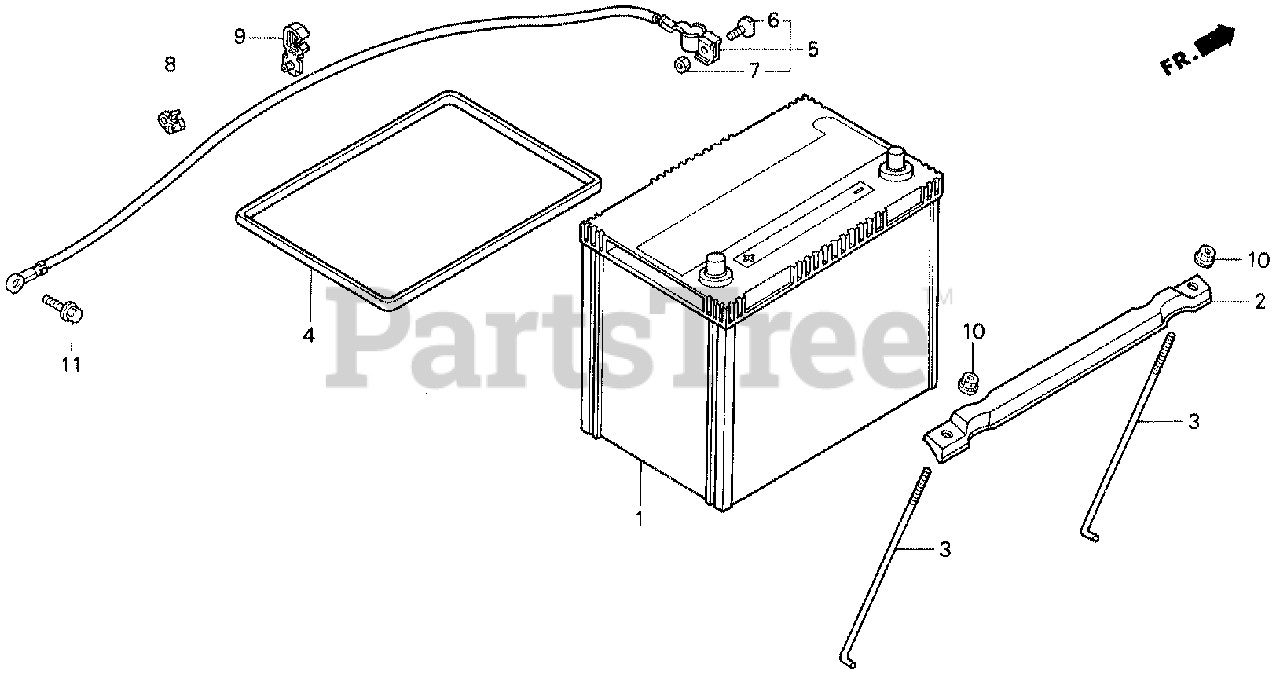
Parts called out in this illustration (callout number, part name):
1	BATTERY ASSY. (55B24R S-MF) (YUASA) (NOT AVAILABLE)
2	PLATE, BATTERY SETTING
3	BOLT, BATTERY SETTING
4	BOX ASSY., BATTERY
5	CABLE ASSY., GROUND
6	BOLT, BATTERY TERMINAL
7	NUT, BATTERY TERMINAL
8	CLIP, WIRE HARNESS (8MM) *NH1* (BLACK)
9	CLIP, HARNESS (5MM-15MM)
10	NUT, FLANGE (6MM)
11	BOLT, FLANGE (8X12)
